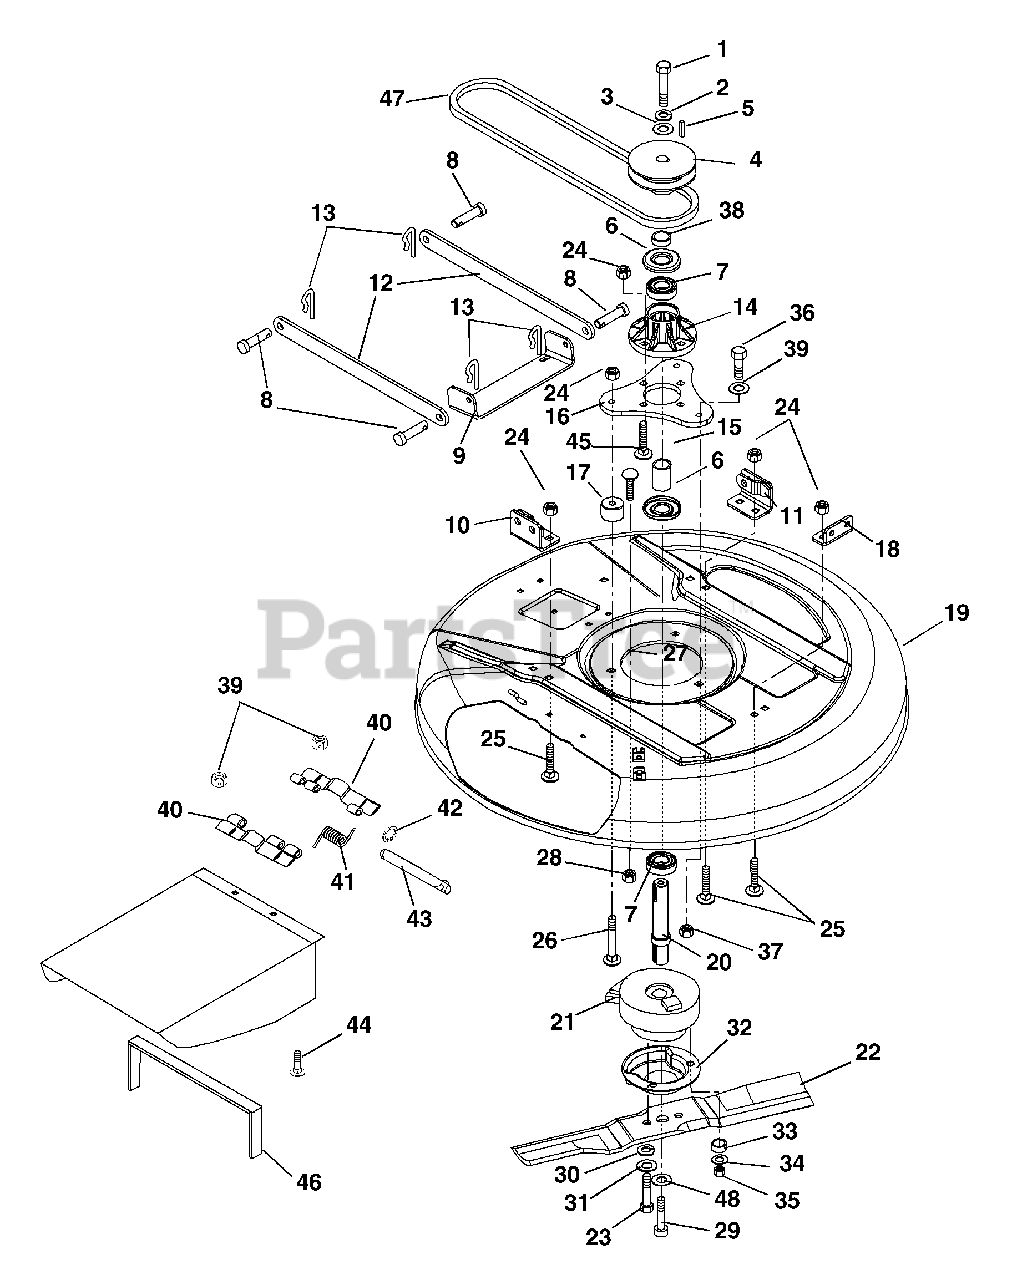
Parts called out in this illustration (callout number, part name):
1	Bolt-Hex .38-16 x 1.00 Grade 8 with Epoxy Patch
2	Washer, Locking .375 x .115 Heavy
3	Washer, Flat Steel .406 x 1.375 x .135
4	Sheave, Spindle- 4.75 Diameter
5	Key, Square .25 x .38 x .25
6	Bearing, Slinger
7	Bearing, Ball 1.00 x 2.00 x .56
8	Clevis Pin, .491/.496 x 1.25
9	Bracket, Rear Hanger 32"
10	Bracket, Deck Link Right Hand
11	Weldment, Deck Link Left Hand
12	Link Stabilizer 32" Decks
13	Clip, Spring
14	Assembly, Spindle Housing
15	Spacer, 1.00 x 1.25 x 1.60
16	Spindle, Mount Plate
17	Spacer, Mounting Plate
18	Bracket, Front Hanger 32"
19	Deck 32"
20	Shaft, 32" Input
21	Clutch Kit
22	Blade, 32" Mower
23	Bolt, Hex M10 x 1.25 x 30
24	Nut, Locking-Top-Flange .38-16
25	Bolt-Round Head Square Neck .38-16 x .75 Grade 5
26	Bolt-Round Head Square Neck .38-16 x 2.25 Grade 5
27	Bolt-Round Head Square Neck .31-18 x 1.50 Grade 5
28	Nut, Spin Lock Flange .312-18
29	Bolt, Button Head .50 x 1.25-20
30	Washer, Locking Metric 10 MM
31	Washer, Flat Steel .406 x 1.00 x .188
32	Shield, Debris
33	Bushing, Bronze .75 I.D. x .88 O.D. x .50 Long
34	Washer, Flat Steel .38 x .875 x .083
35	Nut-Locking-Nylon .38-16
36	Bolt-Hex .38-16 x 3.00 Grade 5
37	Nut-Flange .375-16
38	Spacer Steel 1.01 x 1.38 x .509
39	Nut-Locking-Center .25-20
40	Hinge Plate
41	Spring-Torsion .09 x .37 x .63
42	Ring-Retaining-External .312 x .025
44	Bolt-Round Head Square Neck .25-20 x .75 Grade 5
45	Bolt-Round Head Square Neck .38-16 x 1.25 Grade 5
46	Trim Bulk 0125
47	Belt, Zoom Sport PTO
48	Washer, Flat Steel .50 x 1.75 x .187
